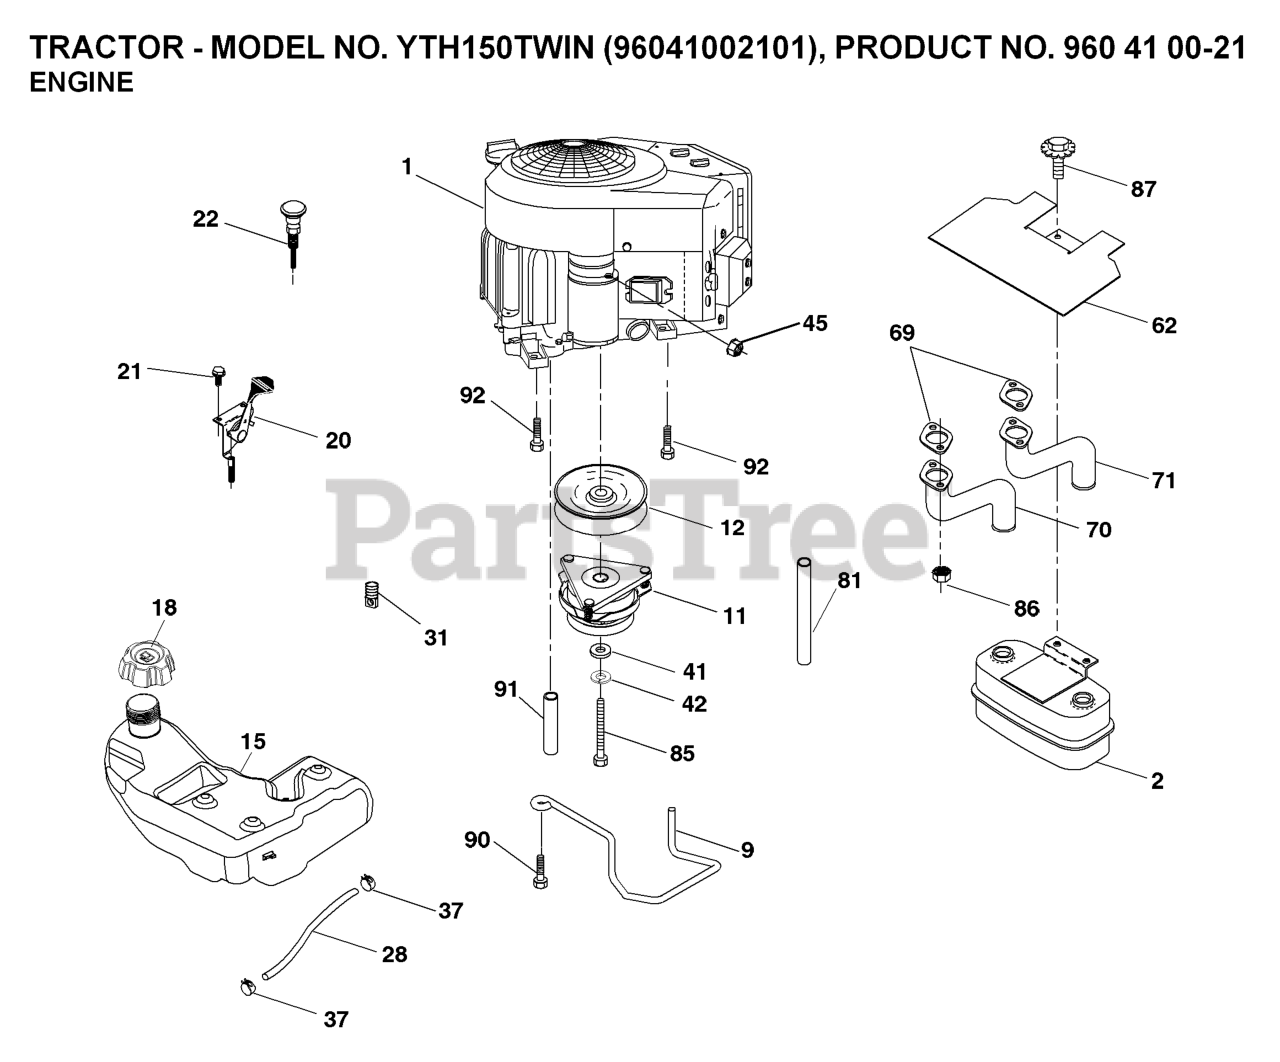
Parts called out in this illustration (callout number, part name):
2	MUFFLER.TWIN.CYL.LOW.TONE
9	KEEPER.BELT.ENGINE.4.2
11	RB.CLUTCH.OGURA.4.4.PD
12	PULLEY.ENGINE.TUFFTORQ
15	TANK.FUEL.4GAL
18	CAP.FUEL.TANK.3"GREY
20	THROTTLE CABLE
21	SCREW
22	CONTROL.CHOKE.ERGO.PUSH-IN.BLA
28	REPL BY 532 00 85-43
29	KIT.SPARK ARRESTOR 794945 B&S
37	HOSE CLAMP
42	LOCKWASHER
45	NUT
62	RP SHIELD HEAT MUFFLER
70	EXHAUST TUBE LH KAWI
71	EXHAUST TUBE RH KAWI
81	TUBE, DRAIN OIL ASM.
85	BOLT HEX 7/16-20X4-1/4"
86	NUT.HEX.FLANGE.TOPLOCK
87	BOLT.5/16-18UNCX1.W/SEMS.BLK
90	SCREW 3/8-16X1
92	SCREW 3/8-16X1
